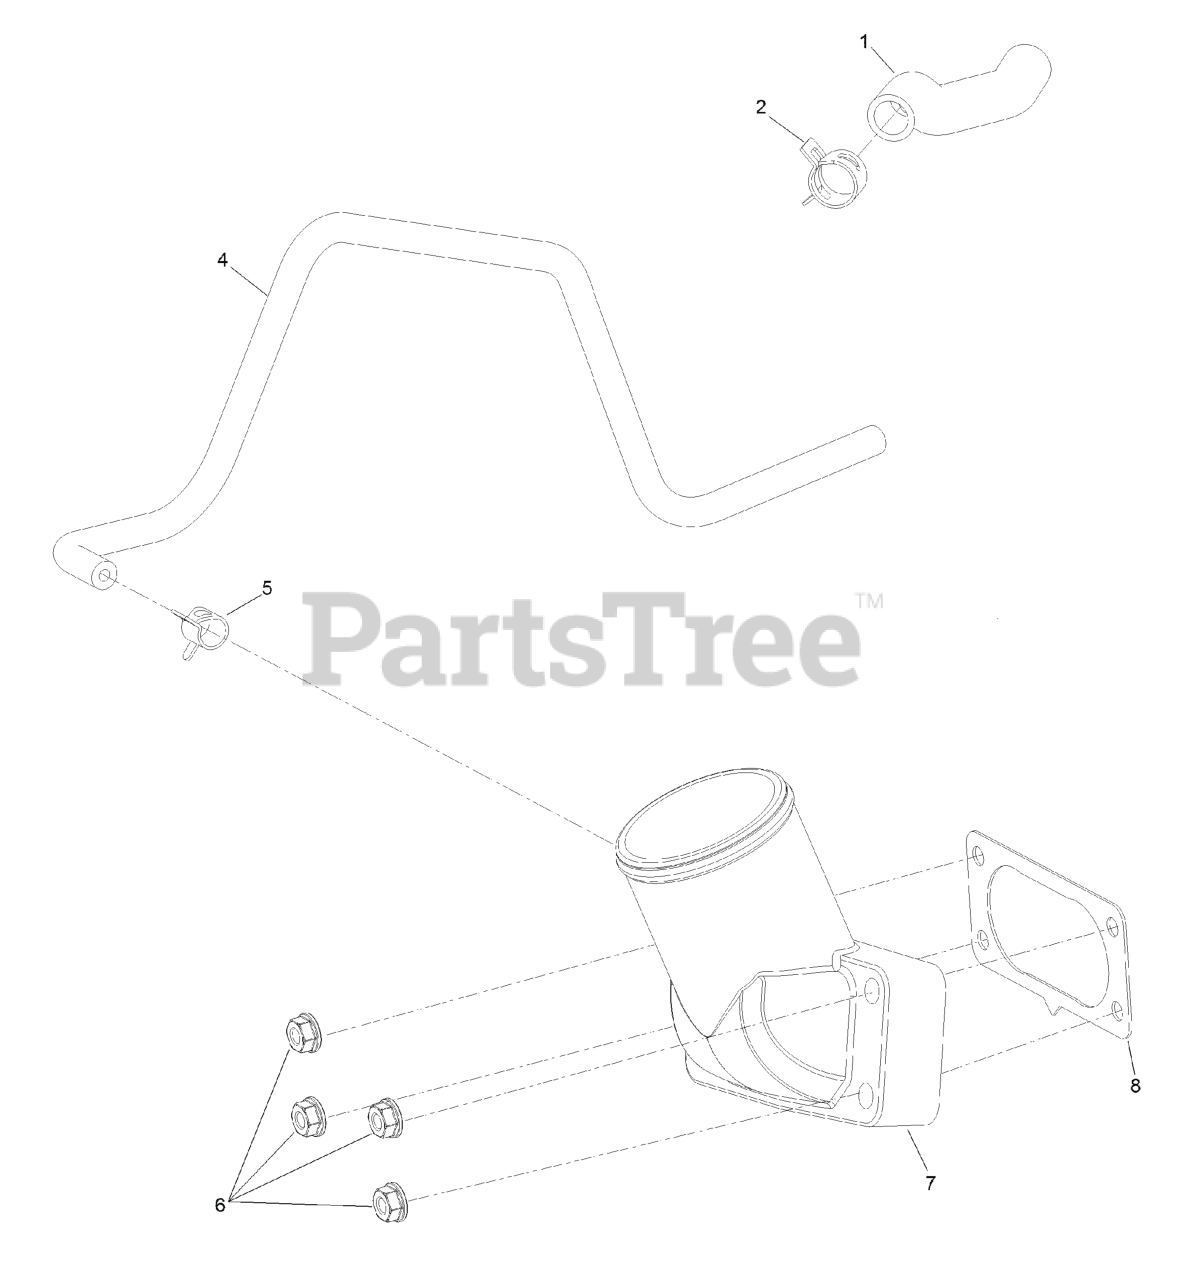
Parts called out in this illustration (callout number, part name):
1	TUBE-BREATHER
2	CLAMP-HOSE
4	HOSE-FUEL
5	CLAMP-HOSE
6	NUT-FLANGE
7	MANIFOLD-INTAKE
8	GASKET-CARBURETOR
